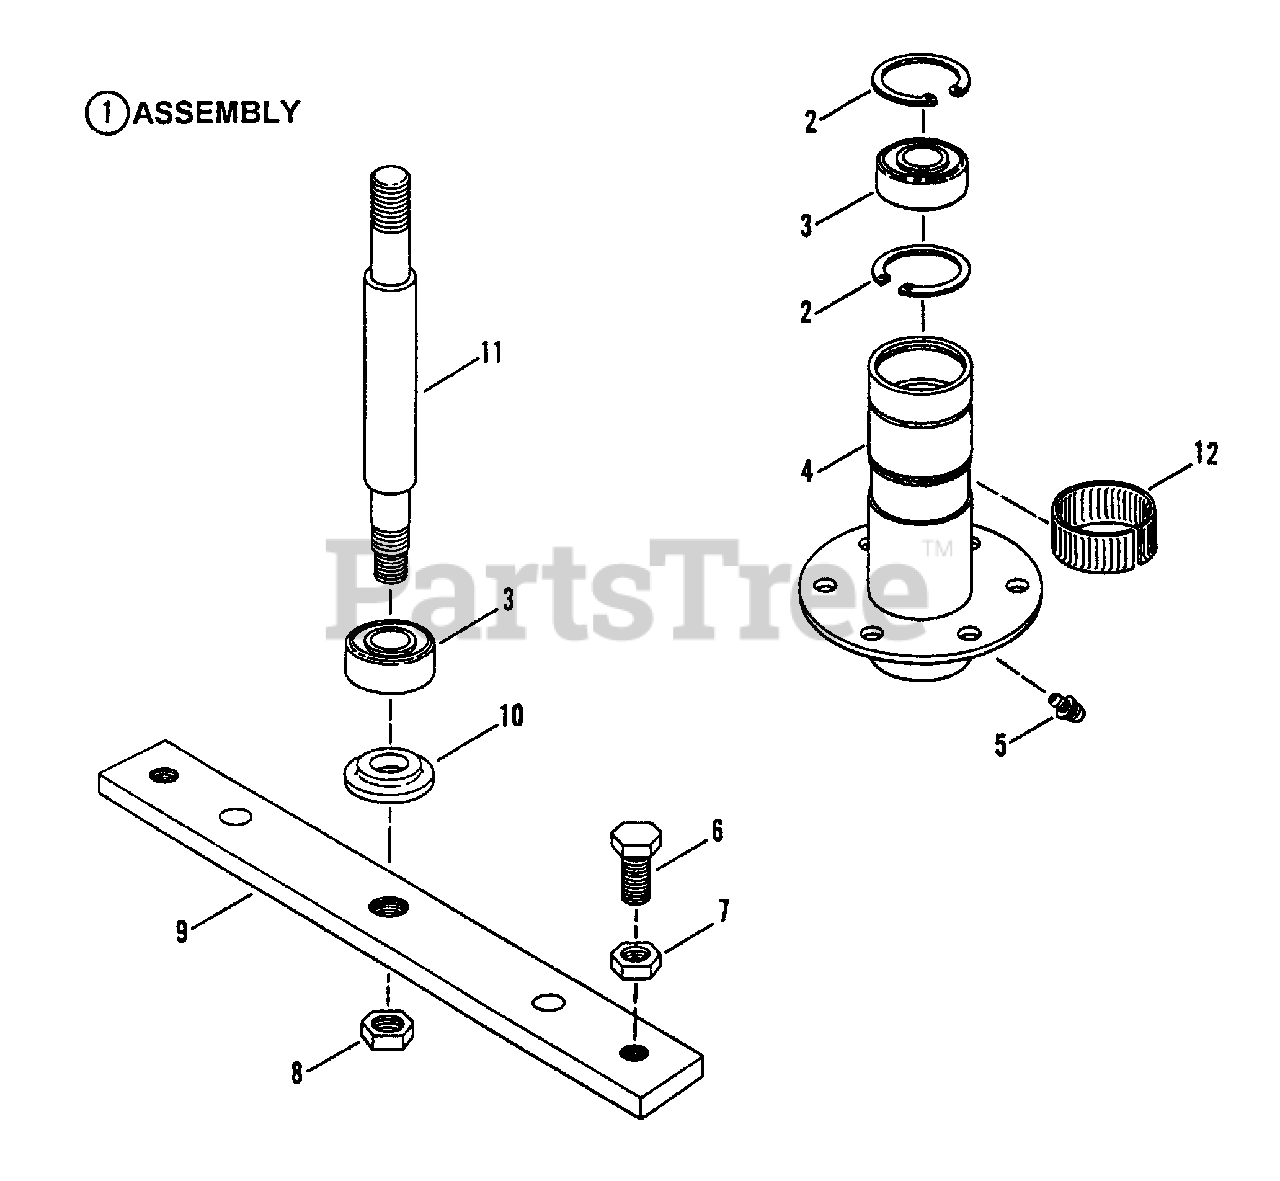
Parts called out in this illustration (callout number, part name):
1	ASSEMBLY, Spindle Housing, 30" Cutting Deck
2	RING, Retaining
3	BEARING, Spindle
4	HOUSING, Spindle
5	FITTING, Lube (Press fit for .187 hole-no ball)
6	SCREW, 1/2-20 x 1-1/4" Hex Head Cap, Grade 5
7	NUT, 1/2-20 Hex Jam
8	NUT, 5/8-18 Hex Center Lock Jam
9	HOLDER, Blade
10	WASHER, Spindle
11	SPINDLE
12	RING, Tolerance
